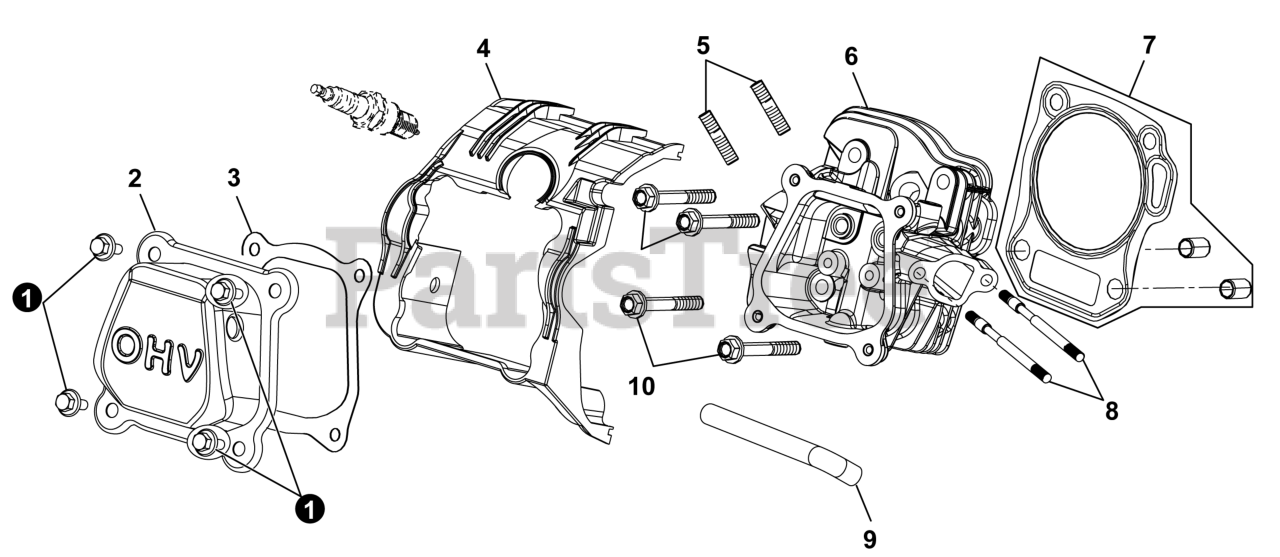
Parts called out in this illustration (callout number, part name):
2	COVER, VALVE
3	GASKET, VALVE COVER
4	SHROUD, CYLINDER BODY
5	STUD, INTAKE
6	HEAD, CYLINDER
7	WEAR PAD, FRONT
9	TUBE, BREATHER
10	BOLT, CYLINDER HEAD
